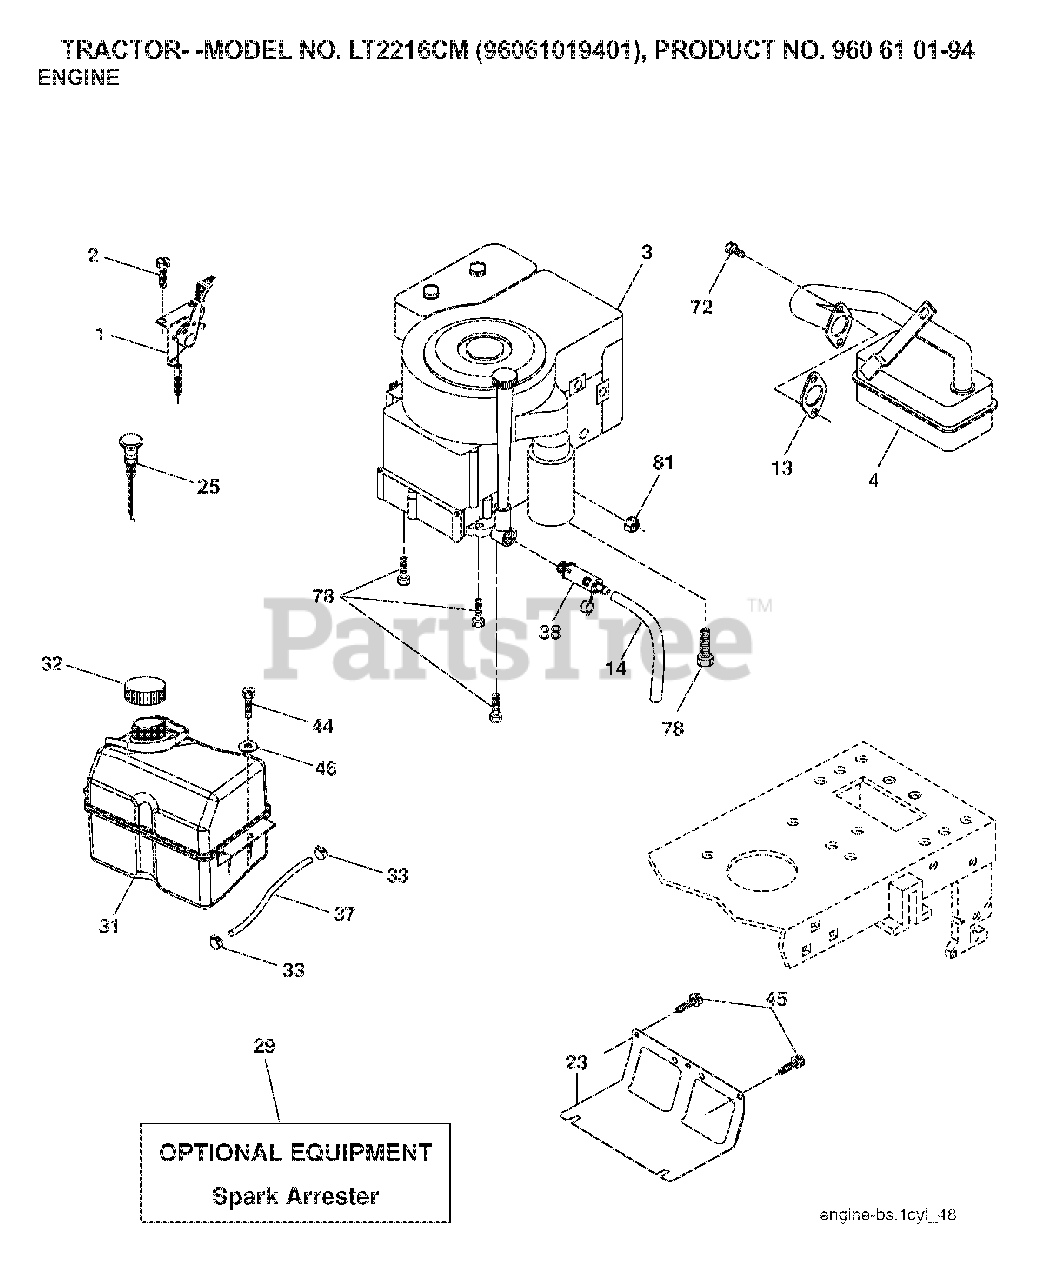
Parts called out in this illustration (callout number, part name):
1	CONTROL TH/CH FLAG
2	SCREW
8	BOLT, 5/16-18 X 1 3/4
13	REPL BY 532 27 22-93
14	TUBE, DRAIN OIL ASM.
23	SHEILD.BROWNING.DBR.GUARD
29	ARRESTER SPARK (OPTIONAL)
31	TANK FUEL
32	FUEL CAP
33	HOSE CLAMP
37	LINE.FUEL.20
38	PLUG DRAIN OIL EASY
44	SCREW HEXWSHR 1/4-20X3/4
45	SCREW, 3/8-16X3/4
72	SCREW.SOCKET HD.5/16-1
78	SCREW.3/8-16
81	NUT
122	SCREW.1/4-20X5/8
123	SCREW, 5/16-18 X 1/2
